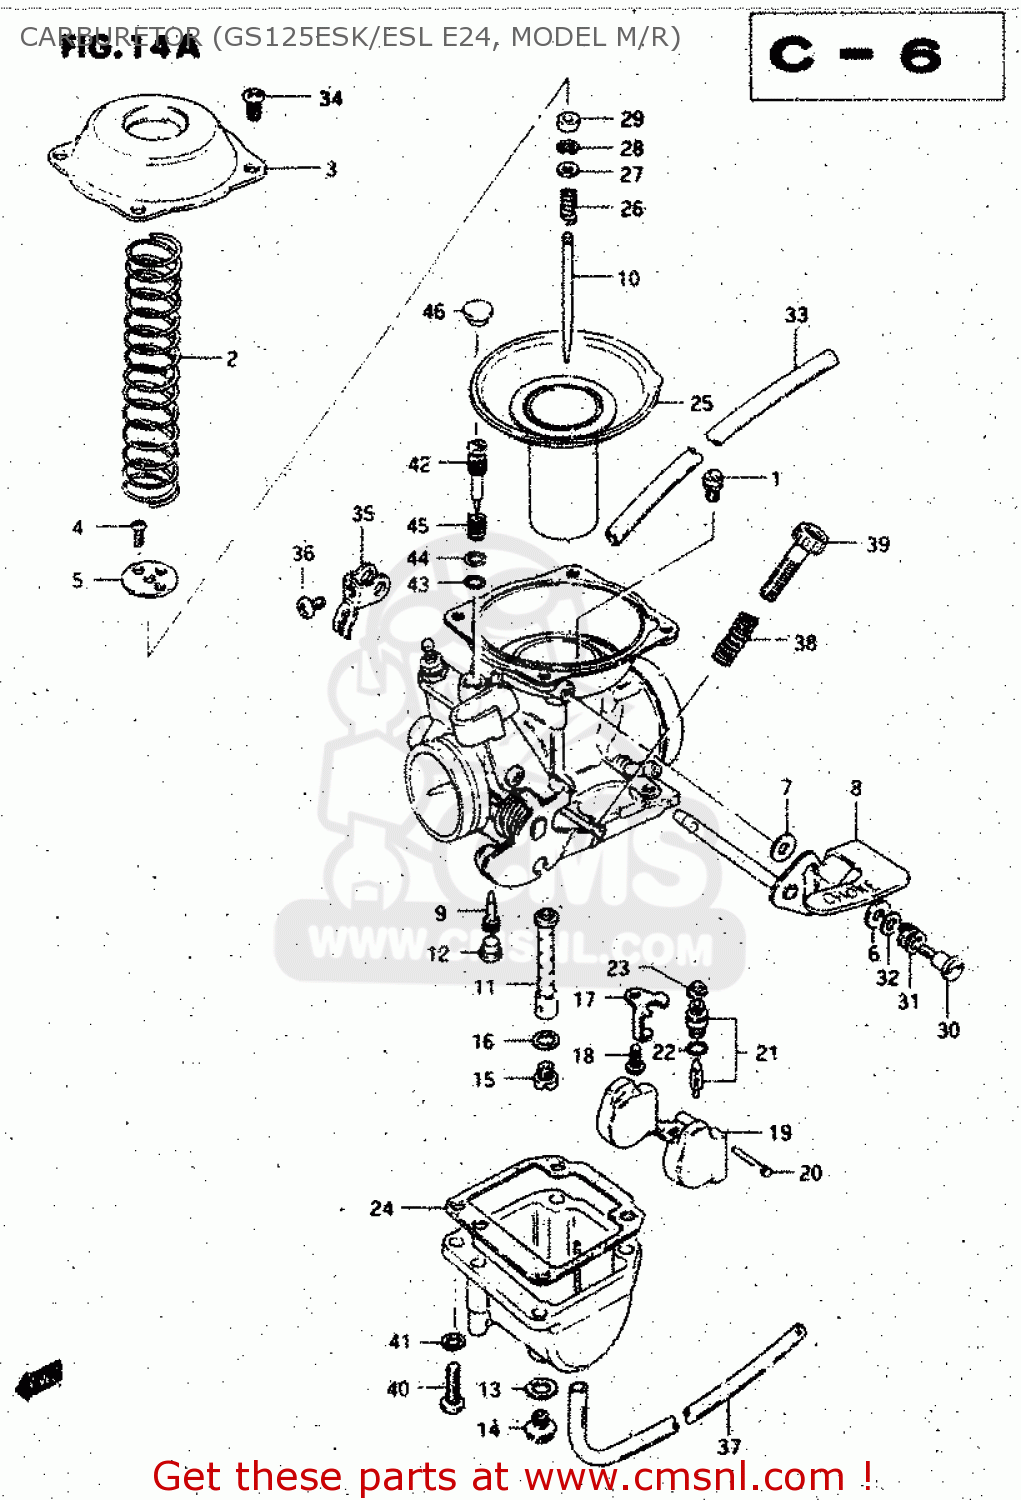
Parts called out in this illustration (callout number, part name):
1	JET,MAIN(180)
2	SPRING
3	COVER
4	SCREW
5	PLATE
6	PACKING (NAS)
7	WASHER,STARTER LEVER (4.1X12X0.8)
8	SHAFT ASSY,STARTER
9	JET,PILOT(35)
10	NEEDLE,JET
11	JET,NEEDLE(P-2)
12	PLUG,NEEDLE JET
13	GASKET (NAS)
14	PLUG,DRAIN
15	JET,MAIN(102.5)
16	WASHER,NEEDLE NOZZLE
17	PLATE
18	SCREW
19	FLOAT
20	PIN,FLOAT
21	VALVE ASSY,NEEDLE
22	O-RING,NEEDLE VALVE
23	FILTER
24	GASKET,FLOAT CHAMBER (NAS)
25	DIAPHRAGM ASSEMBLY
26	SPRING
27	WASHER
28	CLIP
29	RING
30	SCREW
31	SPRING
32	WASHER,STARTER SHAFT
33	HOSE
34	SCREW
35	LEVER
36	SCREW
37	HOSE
38	SPRING,THROTTLE SCREW
39	SCREW,THROTTLE STOP
40	SCREW
41	LOCK WASHER
42	SCREW,PILOT
43	O RING,PILOT AIR SCREW
44	WASHER
45	SPRING
46	PLUG
